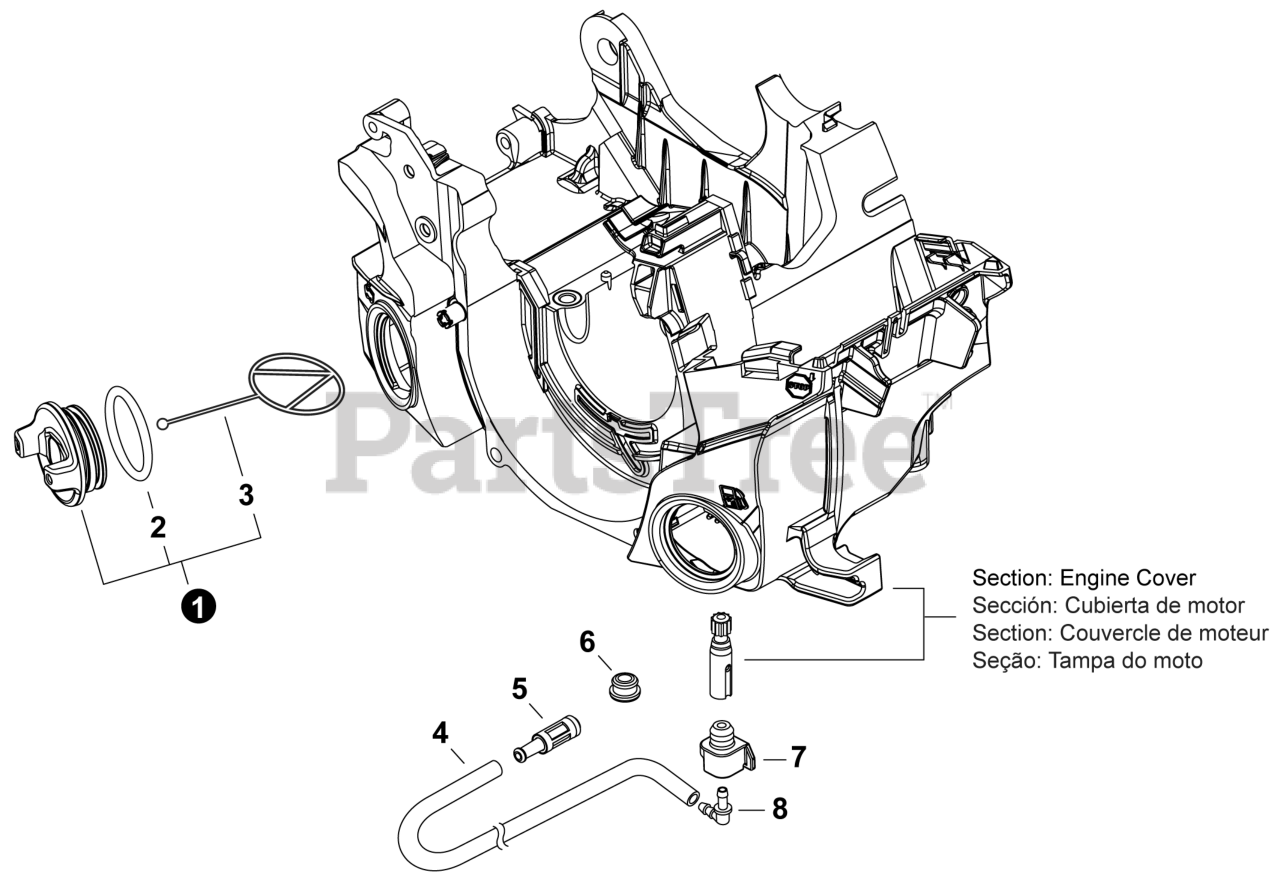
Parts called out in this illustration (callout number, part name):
1	CAP ASSY, OIL
2	O-RING 29
3	CONNECTOR, CAP L= 60 MM
4	PIPE 3x6x210 BLACK
5	FILTER, OIL
7	GROMMET, OIL
8	CONNECTOR, PIPE
